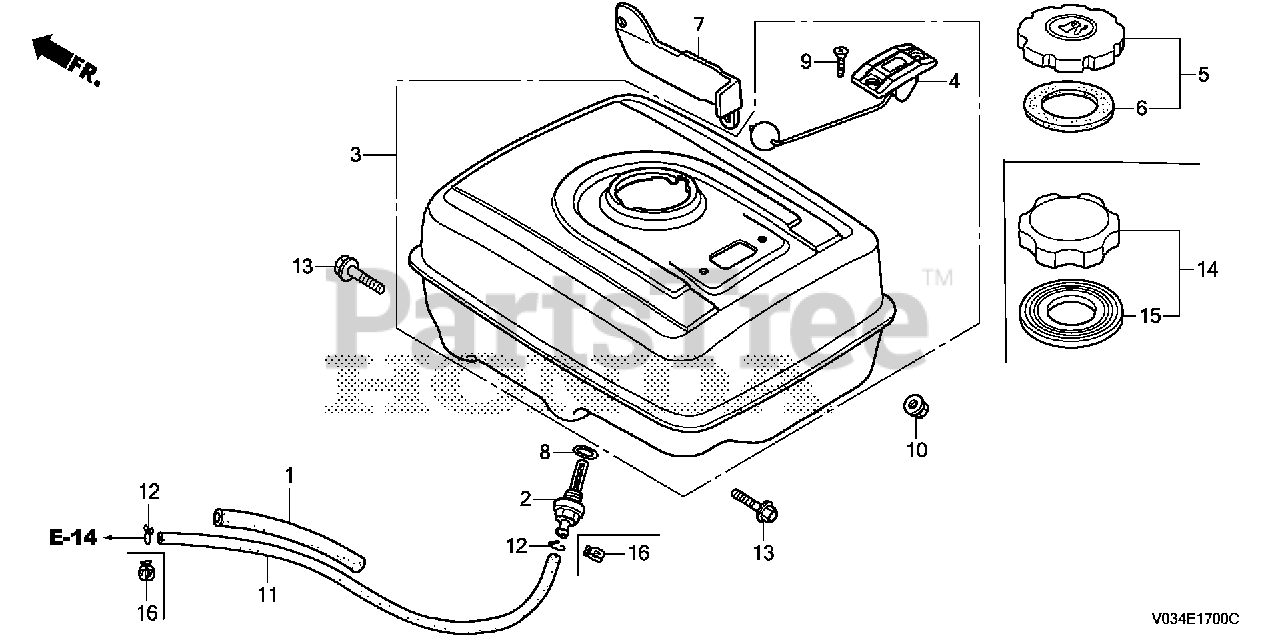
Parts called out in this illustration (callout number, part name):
1	RUBBER, SUPPORTER (107MM)
2	JOINT, FUEL TANK
3	TANK ASSY., FUEL *R280* (GAUGE) (POWER RED)
4	GAUGE ASSY., FUEL
5	CAP, FUEL FILLER (BLACK)
6	GASKET, FUEL FILLER CAP (39X58X3)
7	COVER, SNOW PLATE
8	O-RING (13.5X1.5) (ARAI)
8	O-RING (14MM) (NOK)
9	SCREW, FLAT (5X10)
10	NUT, FLANGE (8MM)
11	TUBE, FUEL (4.5X235) (FKM)
12	CLIP, TUBE (B8)
13	BOLT, FLANGE (8X28)
14	CAP, FUEL FILLER (CHROME PLATED)
15	GASKET, FUEL FILLER CAP (39X62X3) (TOUYOUSYA)
16	CLAMP, TUBE (D8)
